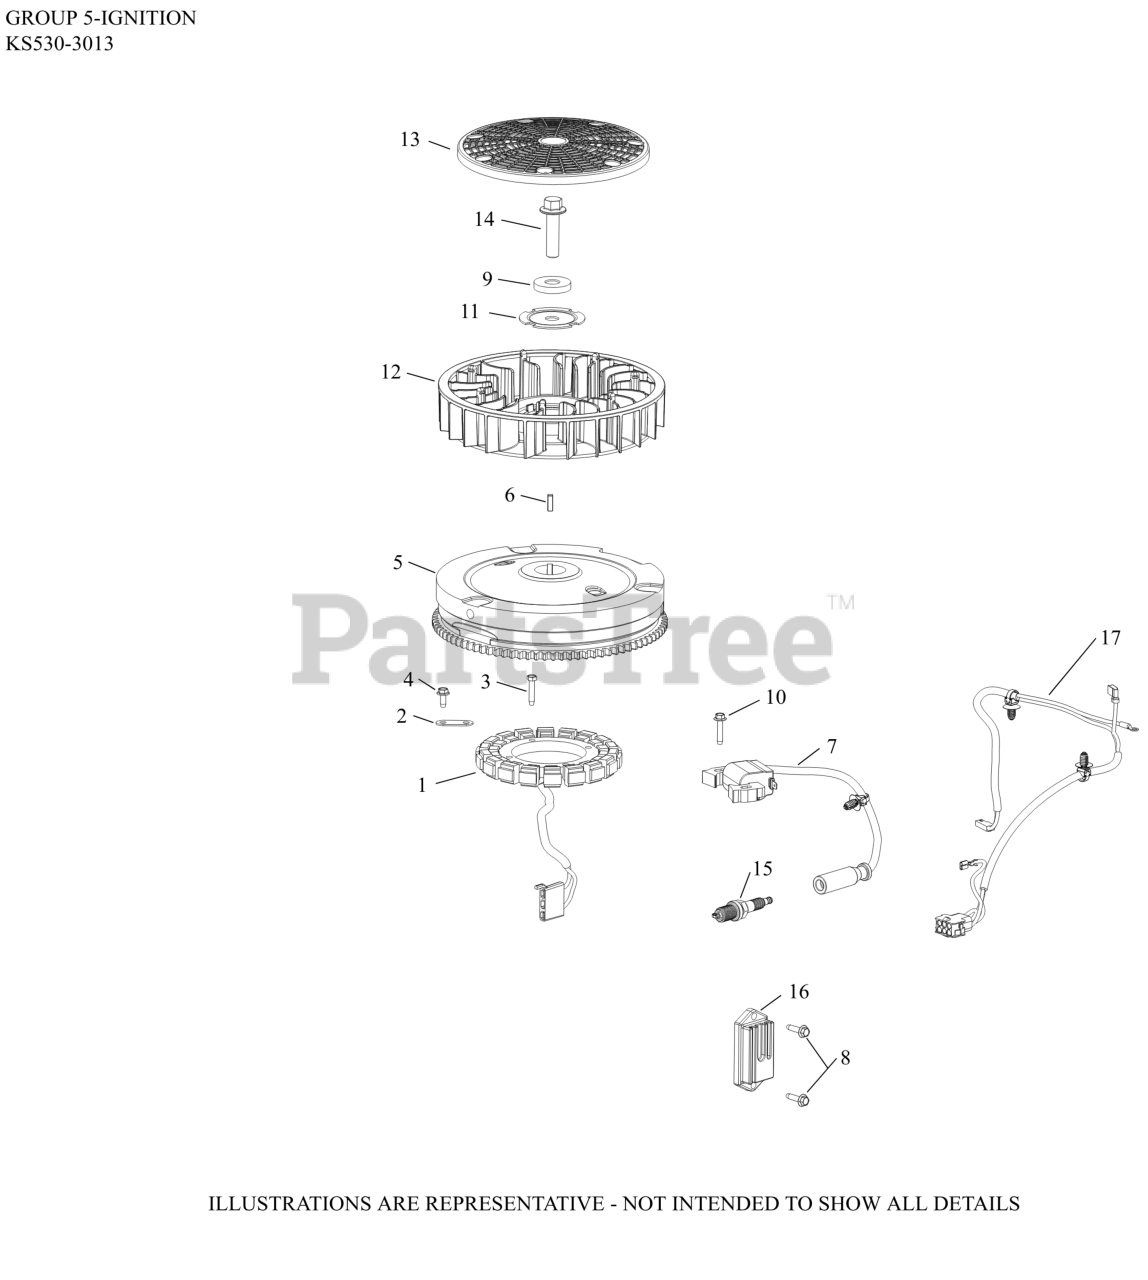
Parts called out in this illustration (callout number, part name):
1	STATOR ASSY, 12A
2	CLIP, STATOR WIRE
3	SCREW, THREAD FORMING
4	SCREW, FLG THD FRM M5X0.8X13
5	FLYWHEEL, ASSY
6	KEY, SQUARE
7	MODULE, INDUCTIVE IGNITION COIL
8	SCREW, THD FRM-USE 25 086 473-S
9	WASHER, FLAT
10	SCREW, THREAD FORMING
11	PLATE, FAN MOUNTING
13	SCREEN, GRASS
14	SCREW, HEX FLANGE
15	PLUG SPARK 12MM RFI
16	REGULATOR/RECTIFIER 12/15A HALF-WAVE STD
17	HARNESS, WIRING NON-OSU, NON MTD
